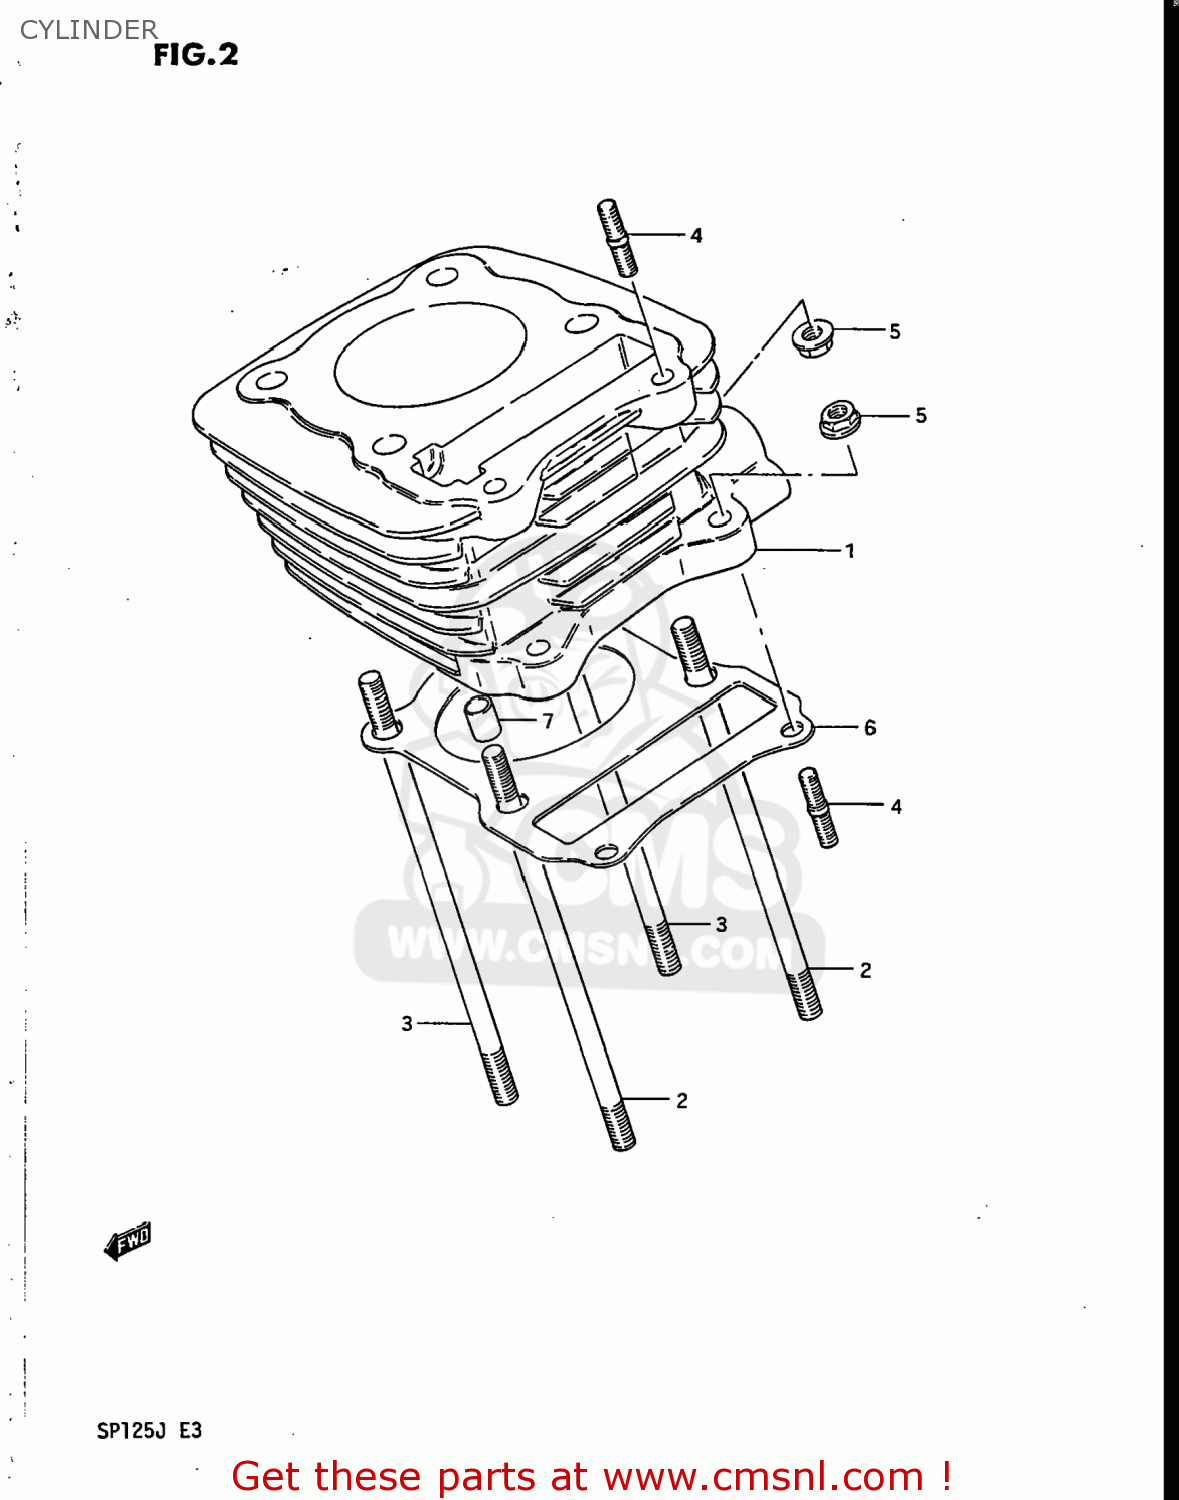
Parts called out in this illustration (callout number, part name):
1	CYLINDER
2	BOLT,STUD
3	BOLT,STUD
4	STUD 6X25
5	NUT 6MM
6	GASKET,CYLINDER (MCA)
7	PIN
